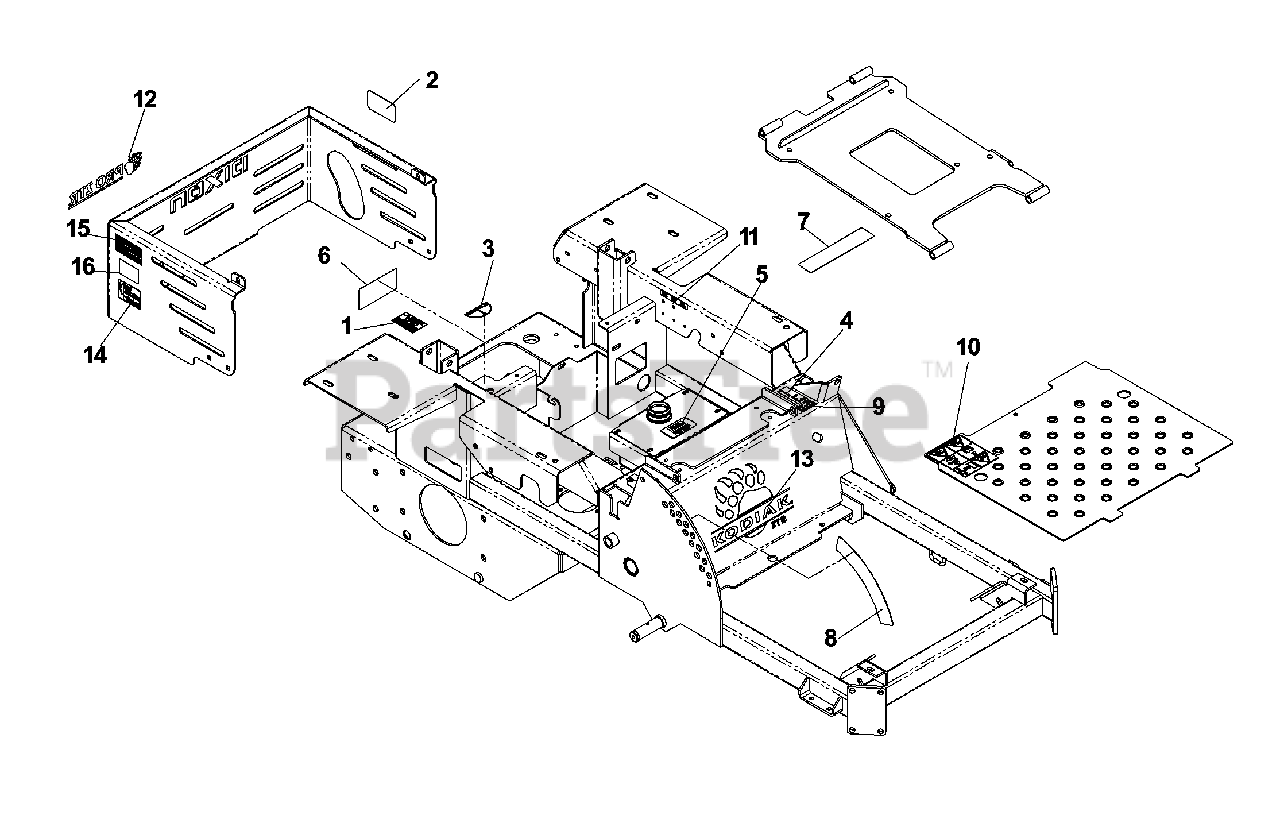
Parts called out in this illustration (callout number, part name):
1	DECAL, EXHAUST
2	DECAL, PROP. 65
3	DECAL, FUEL VALVE
4	DECAL, MOTION CONTROL
5	DECAL, MOBIL 1
6	DECAL, BELT DRIVE
7	DECAL, BATTERY
8	DECAL, HEIGHT ADJ
9	DECAL, F.S.T.
10	DECAL, WARNING
11	DECAL, RELAYS
12	DECAL, PRO ZTR
13	DECAL, KODIAK
14	DECAL, PARKER
15	DECAL, FLAG
